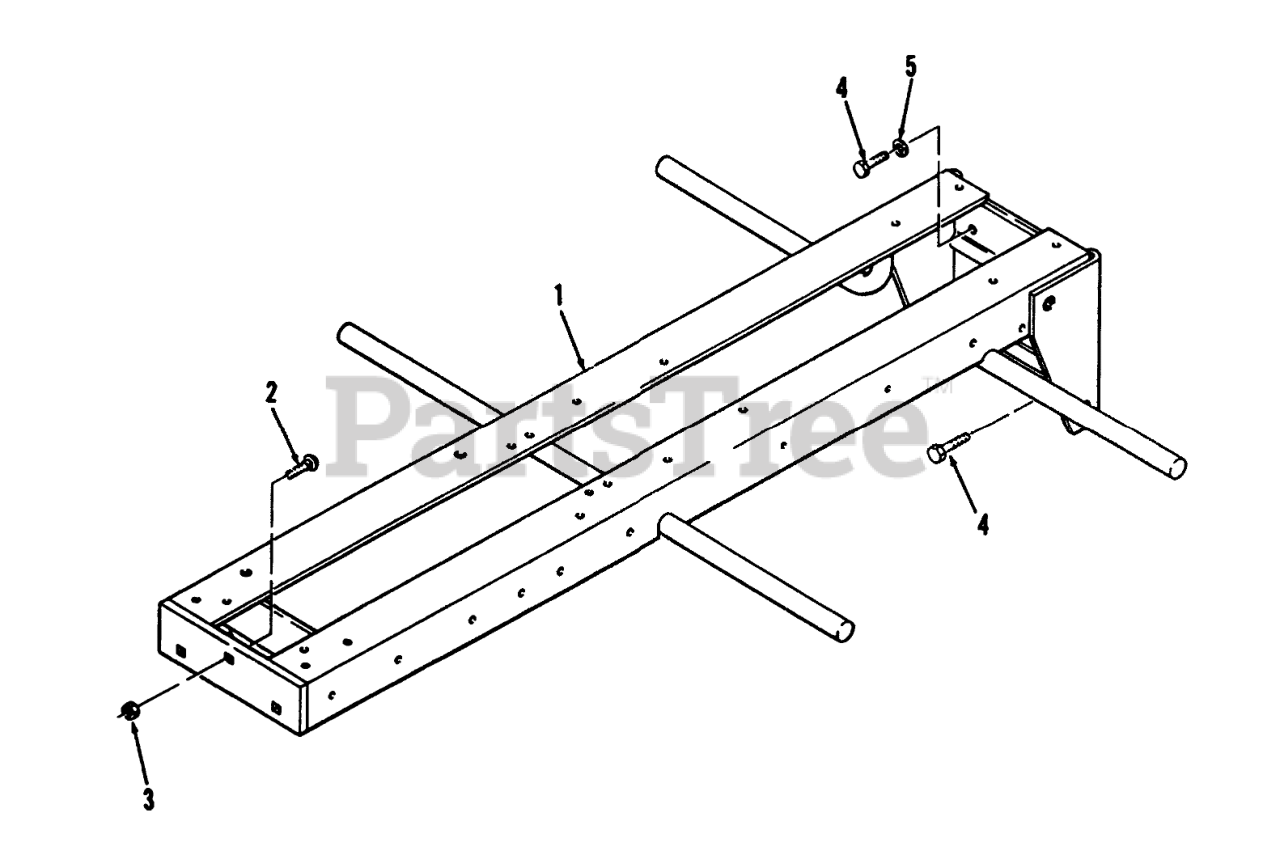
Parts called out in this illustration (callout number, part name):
1	WLDMT-FRAME R
2	BOLT-CARR
3	NUT-LOCK, NI
4	SCREW-HH
5	Washer-Lock 3/8
